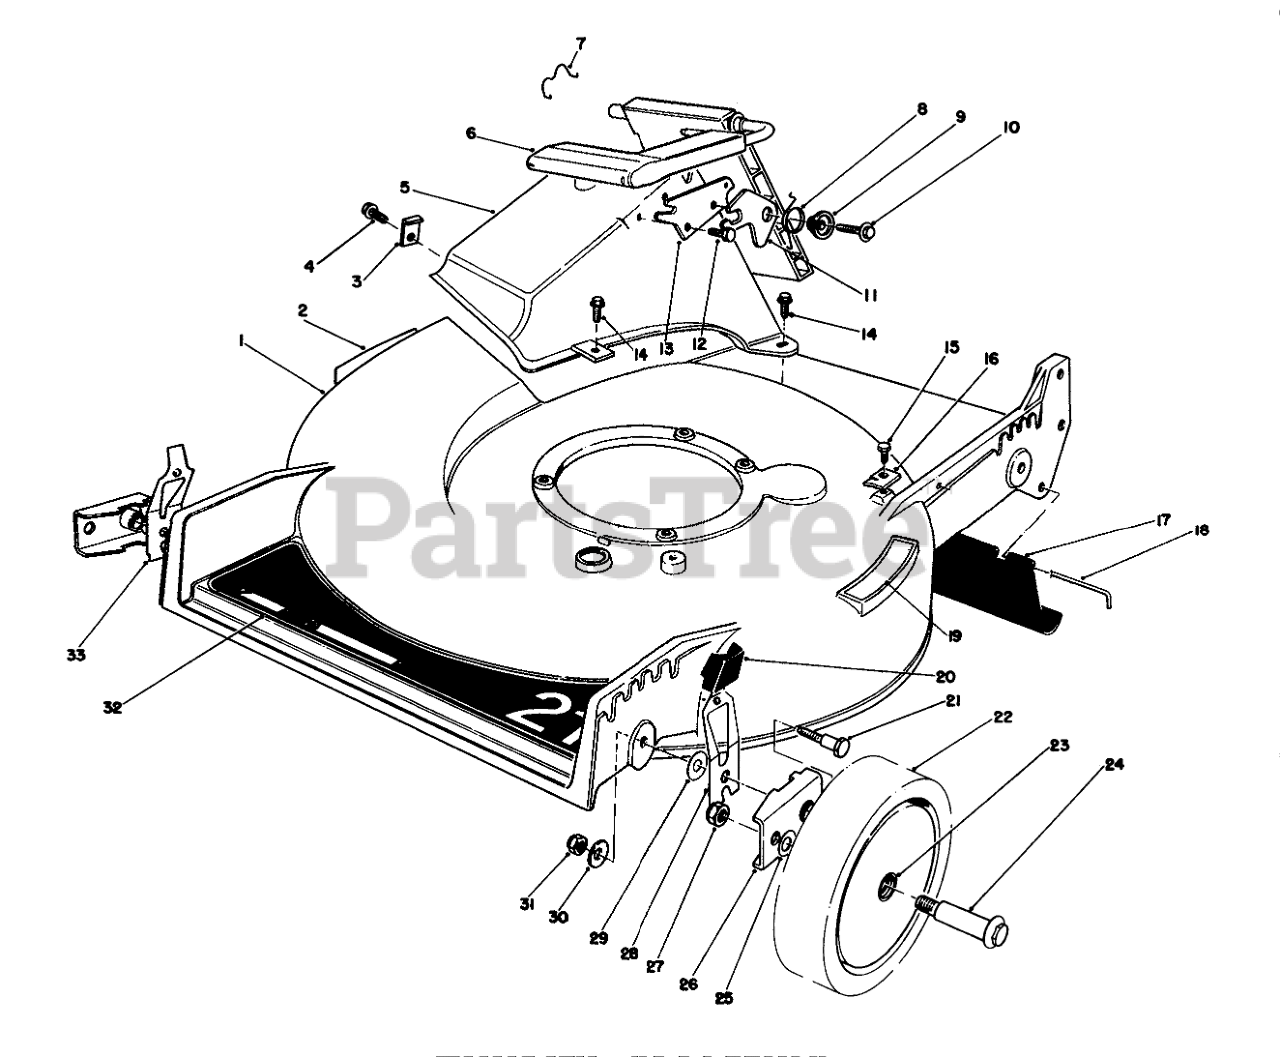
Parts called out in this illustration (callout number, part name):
1	Housing-21" (Incl. Ref. #2 & 19)
2	DECAL-DANGER
3	TUNNEL CLIP
4	SCREW
5	Tunnel Discharge
6	Discharge Door Assembly
7	DOOR RET SPRING
8	TORSION SPRING
9	DOOR SPACER
10	SCREW-HWH
11	SAFETY LATCH
12	SCREW-PLASTITE
13	DOOR LATCH PLATE
14	SCREW-HWH
15	SCREW-HWHTF
16	CLAMP-CABLE
17	SHIELD-TRAILING
18	ROD-SHIELD
19	STEP PAD DECAL
20	KNOB-ARM
21	PIVOT SCREW
22	Wheel & Tire Assembly (Incl. Ref. #23)
23	BUSHING
24	BOLT-WHEEL
25	WASHER
26	HP PIVOT ARM ASM
27	Nut
28	L. HP SPRING ARM ASM
29	WASHER-PIVOT
30	WASHER-BELLEVILLE
31	NUT-LOCK, NI
32	DECK DECAL
33	R HP SPRING ARM ASM
